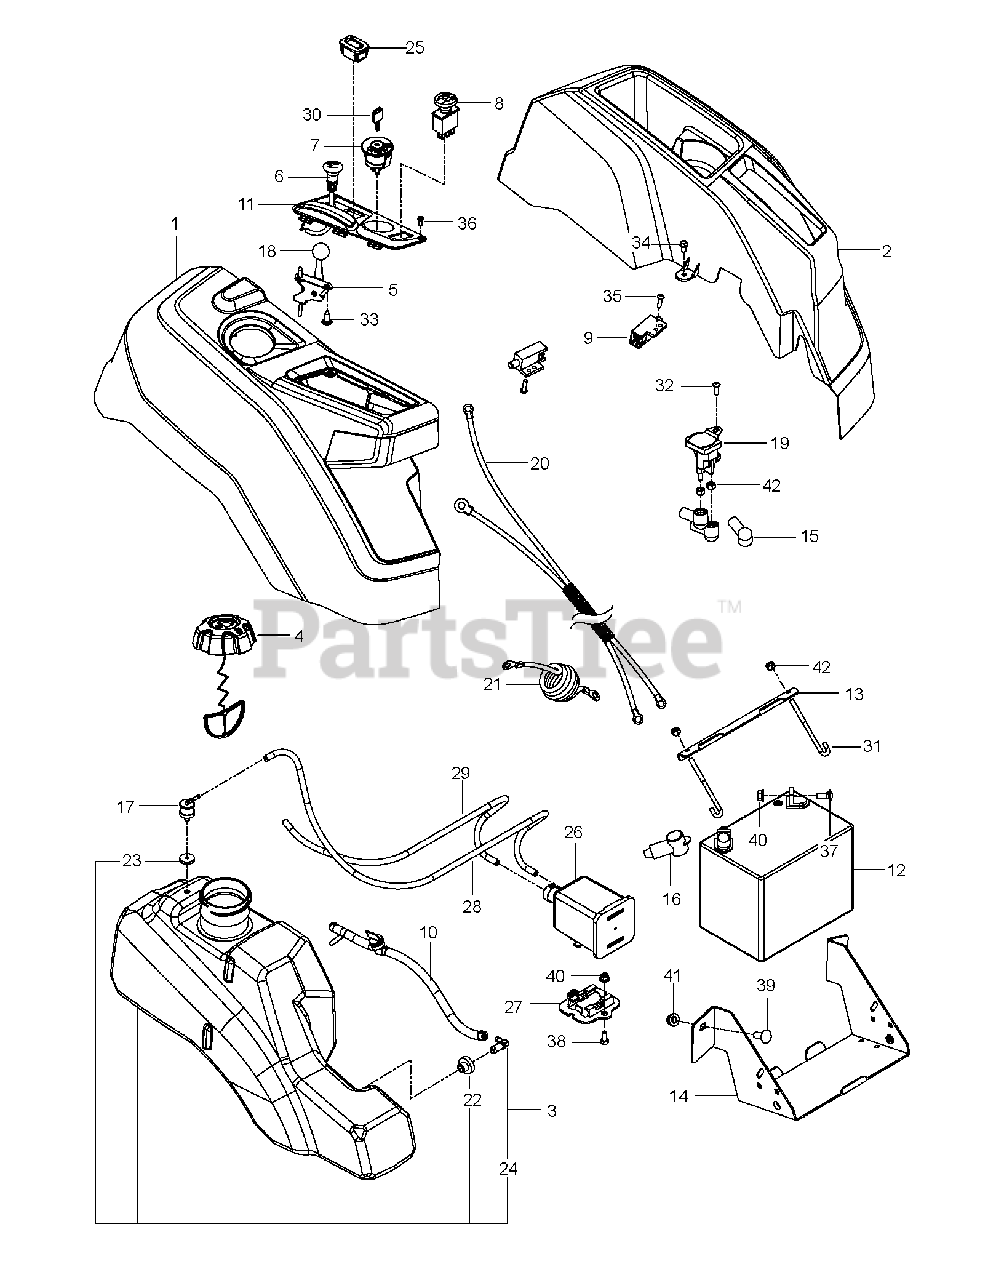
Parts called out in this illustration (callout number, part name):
1	CONSOLE.ASSY.RZ.REFRESH.RH
2	CONSOLE.LH.ASM
3	ASM.FUEL.TANK.LG.3".W/O SHIELD
4	CAP ASSY FUEL 3" GRAY
5	THROTTLE CABLE
6	CHOKE.PUSH-IN.STYLE
7	RP IGNITION SWITCH
8	RP SWITCH.PTO.TERMINAL.STD.RED
9	SWITCH.INTLK.RZ.RFRSH.BUTTON
10	FUEL.HOSE.SHUT.OFF.ASM.10".18"
11	CONTROL.PANEL.RZ.REFRESH.RH
12	BATTERY, 12 V 300 AMP
13	BRACKET.PNT.MOUNT.BATTERY.EDIP
14	BOX.PNT.BATTERY.RZ.EDIP
15	TERMINAL COVER
17	VALVE.FUEL.CHECK
18	KNOB.ROUND.BALL.BLACK
19	SOLENOID.W/BRASS.PLUNGER
20	HARNESS.BTTRY.CABLE.RZ.REFRESH
21	CABLE BATTERY POS RZ
22	BUSHING OUTLET T
23	GROMMET.ROV.SENTEC
24	STEM FUEL TANK
25	GUAGE.SRVCMNDR.HRMTR.
26	CANNISTER, CARBON
27	BRACKET, CANISTER
28	HOSE.3/16".VAPOR.LINE.50"LGTH
29	HOSE.3/16".VAPOR.LINE.36"LGTH
30	KEY MLD GEN DELTA
31	HOOK.J.BATTERY
32	SCR 1/4-20 X 5/8 BTN SKT HD ZD
33	SCREW.PAN.HEAD.#10
34	SCREW
35	SCREW.BUTTONHD.10-24X1/2.(2 2)
36	SCREW 6-19X.437
37	BOLT 5/16-18 X3/4 ZN/YEL GR 5
38	HCS 5/16-18 X 5/8 GR 5 ZD
39	RHSNB 3/8C X 1
40	5/16-18 NYLOC FLANGE NUT
41	NUT 3/8-16 HEX FLG NYLOC ZD
42	LOCKNUT.NYLOC.1/4-20
